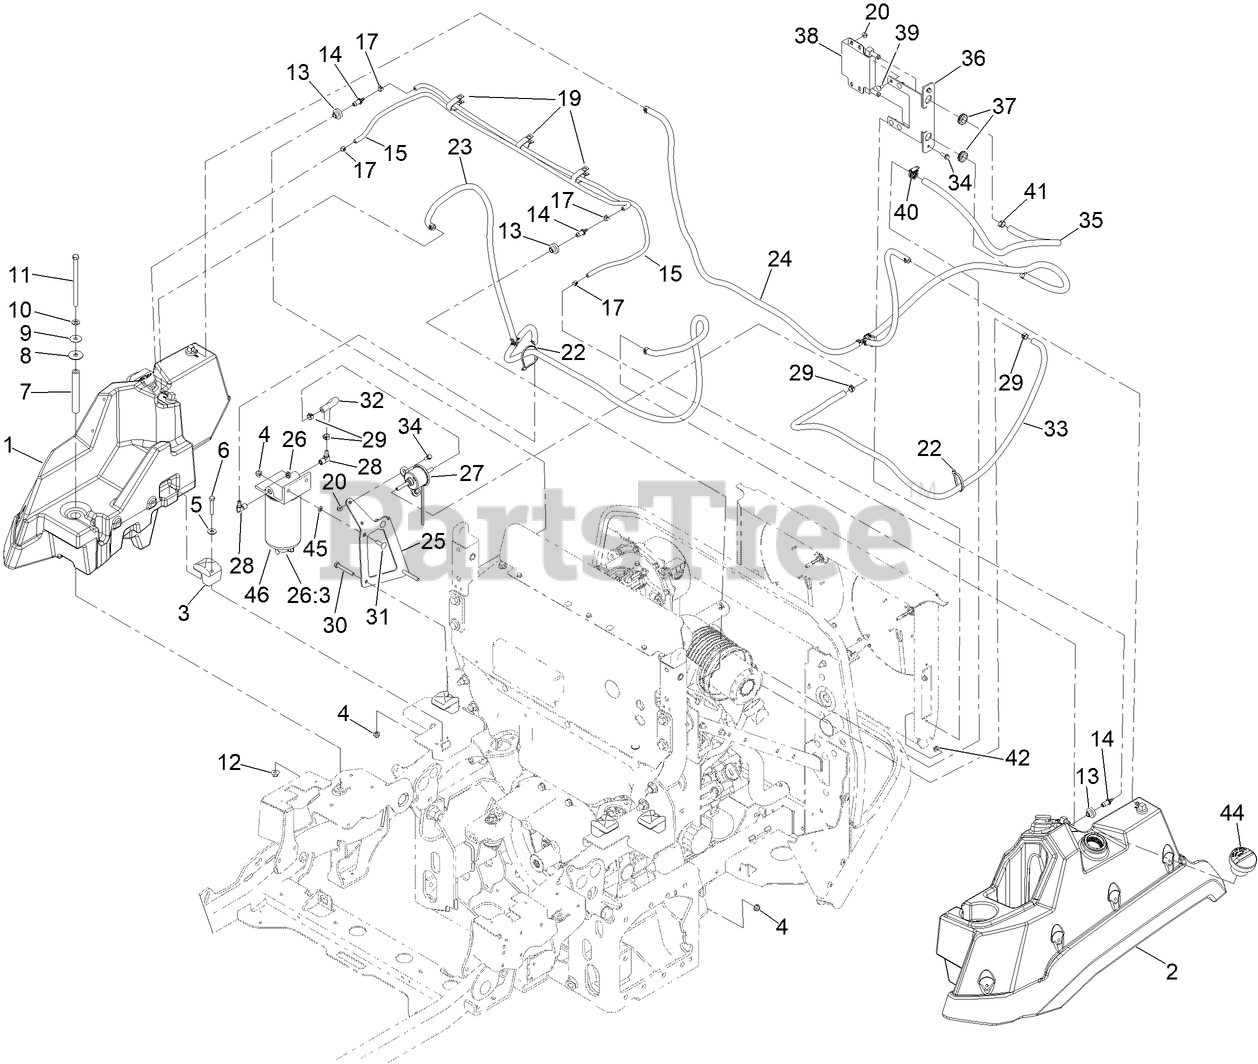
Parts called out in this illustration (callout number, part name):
1	RH FUEL TANK ASM
2	ASM-FUEL TANK, LH
4	NUT-HF, NI
5	WASHER-FLAT
6	SCREW-HH
7	TUBE-SPACER
8	WASHER-RUBBER
9	WASHER-PLAIN
10	WASHER-FLAT
11	SCREW-HH
12	NUT-HF, NI
13	BUSHING
14	FITTING-ORIFICE, STRAIGHT
15	HOSE-VENT, TANK
17	CLAMP-HOSE
19	CLAMP-HOSE
20	NUT-HF
22	TIE-CABLE
23	FUEL SUCTION LINE ASM
24	HOSE ASM-FUEL, TEE
25	BRKT-FUEL FILTER
26	FILTER-FUEL/WATER SEPARATOR
26:3	FILTER-BOWL, WATER SEPARATOR
27	PUMP-FUEL, ELECTRIC
28	FITTING-HYD, 90
29	CLAMP-HOSE
30	SCREW-HH
31	SCREW-CARR
32	HOSE-FUEL
33	HOSE-FUEL
34	SCREW-HWH
35	HOSE-FUEL
36	MOUNT-COOLER, FUEL
37	GROMMET
38	COOLER-OIL
39	SCREW-CARR
40	CLAMP-HOSE
41	CLAMP-HOSE
42	NUT-HF
44	CAP-FUEL, DIESEL ULTRA LOW SULFUR
45	RING-RETAINING, BOLT
46	FILTER-FUEL/WATER SEPARATOR
